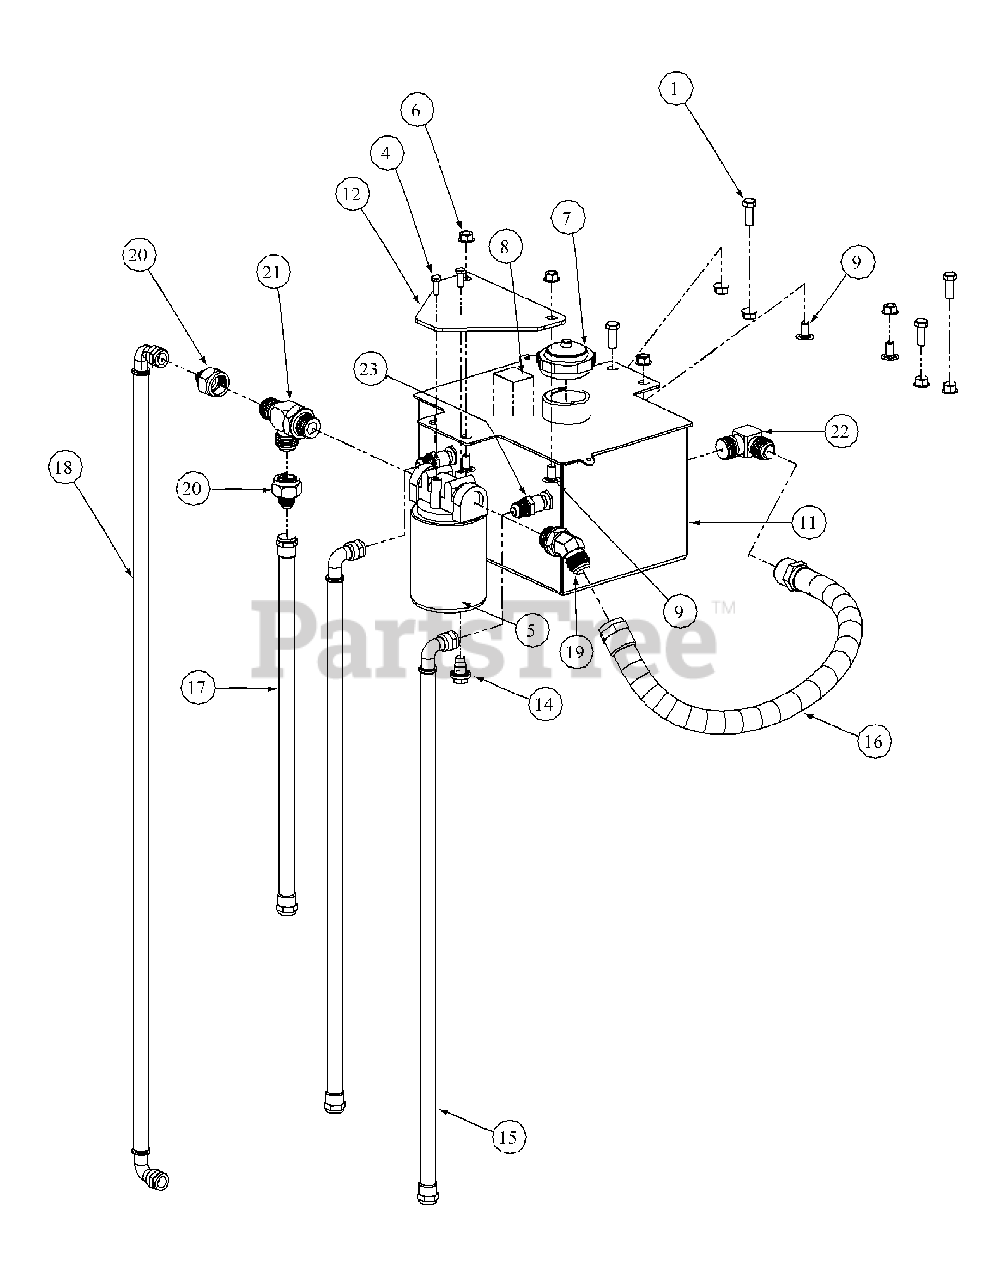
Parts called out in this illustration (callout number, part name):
1	Hex Cap Screw, 3/8-16, 1
3	Protective Hose Cover
4	Hex Cap Screw, 1/4-20, .75
5	Filter Head 3/4
6	Hex Nut Flange Lock, 3/8-16
7	Cap, Hydro Oil Tank
8	Decal Oil Only 20W50
9	Carriage Bolt, 3/8-16 x .75 LG.
11	Hydraulic Tank Assembly
12	Mounting Plate Oil Filter
14	Oil Pan Drain w/ Seal and Plug
15	Gearbox to Tank Hose Assembly
16	Tank to Filter Hose Assembly
17	Filter to LH Pump Hose Assembly
18	Filter to RH Pump Hose Assembly
18	Drive System Fluid Plus, Quarts
18	Drive System Fluid Plus, Gallons
19	Connector, 3/4 x3/4
20	Adapter 3/4 x 1/2
21	Fitting Tee, 3/4 x 3/4 x 3/4
22	Fitting Elbow, 1/2 x 1/2
23	Fitting, 3/8" NPT, 1/2" Flare
